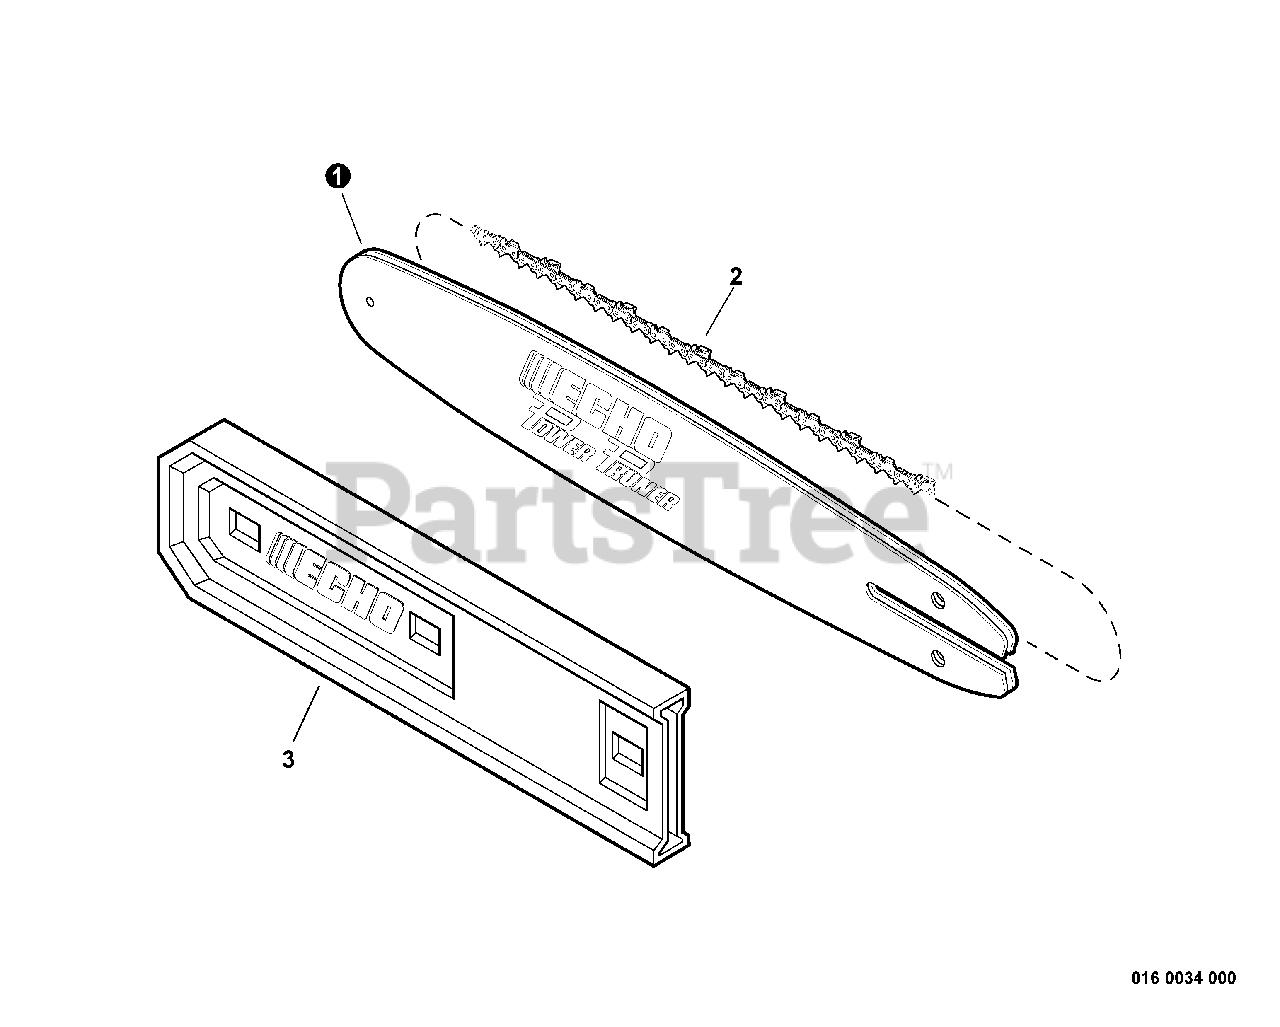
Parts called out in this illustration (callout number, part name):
1	GUIDE BAR - 12"
2	SAW CHAIN 12" 0.043" GA
3	SCABBARD 12"
